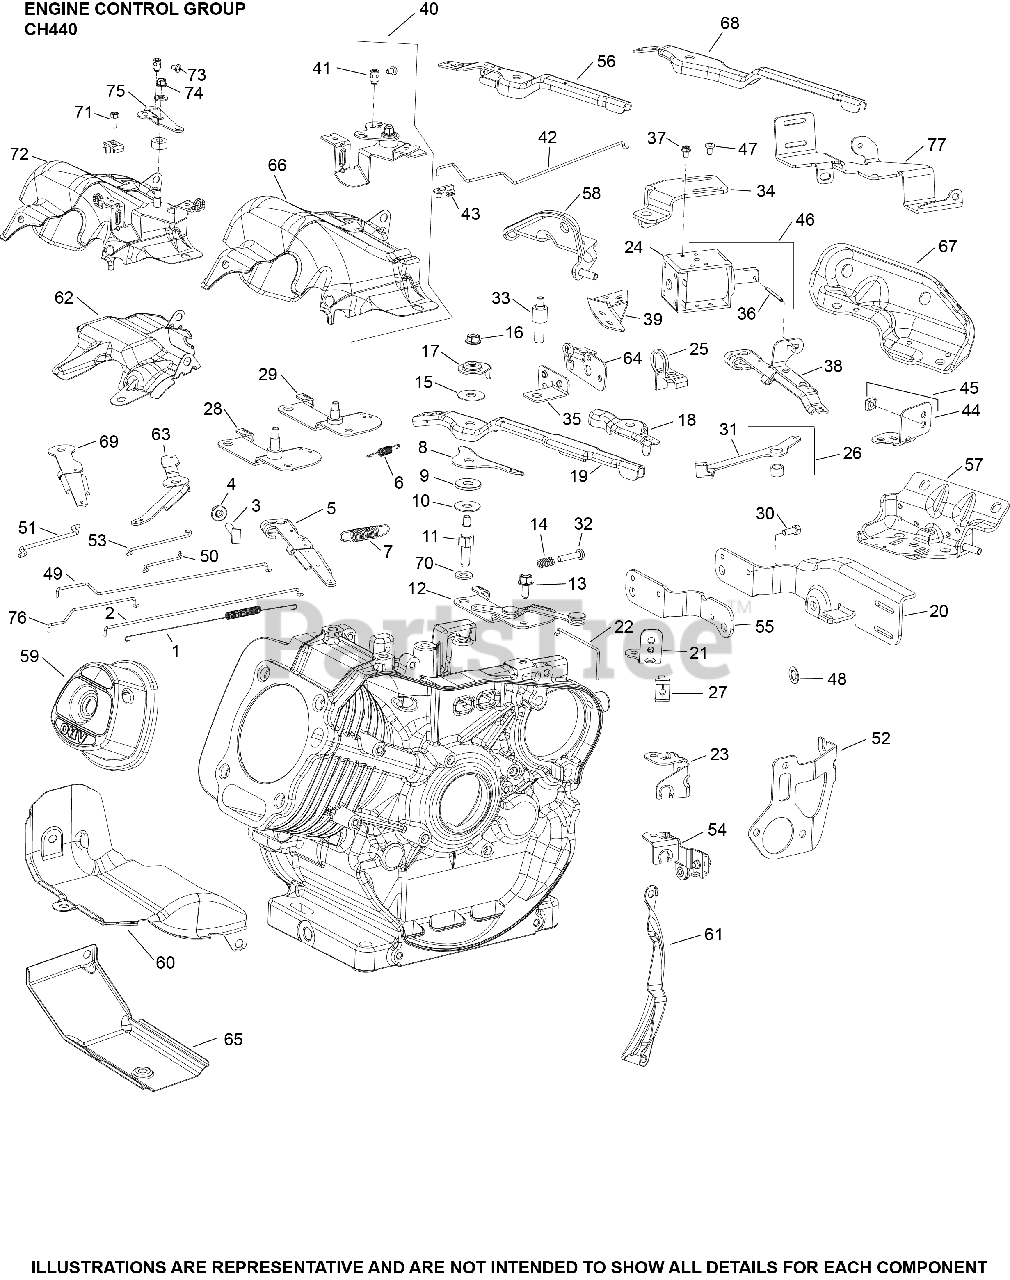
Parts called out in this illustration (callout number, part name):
1	SPRING, LINKAGE
2	LINKAGE, GOVERNOR
3	SCREW, RECTANGLE HEAD (M6)
4	NUT, HEX FLANGE (M6) - USE 14 100 16-S
5	LEVER, GOVERNOR
7	SPRING, GOVERNOR
8	LEVER, FIXED SPEED
14	SPRING, COMPRESSION
16	NUT, HEX FLANGE LOCK (M6)
27	CLAMP, CABLE
32	SCREW, SPEED ADJUSTING (CKY)
33	STUD, CONTROL LEVER
34	BRACKET, IDLE DOWN SOLENOID
35	BRACKET, CONTROL
38	LEVER ASSEMBLY, GOV. IDLE PULL DOWN
44	BRACKET, REMOTE CHOKE
45	BRACKET REMOTE, CHOKE ASSEMBLY
46	KIT, SOLENOID IDLE
47	SCREW, SET HEX FLANGE HEAD
